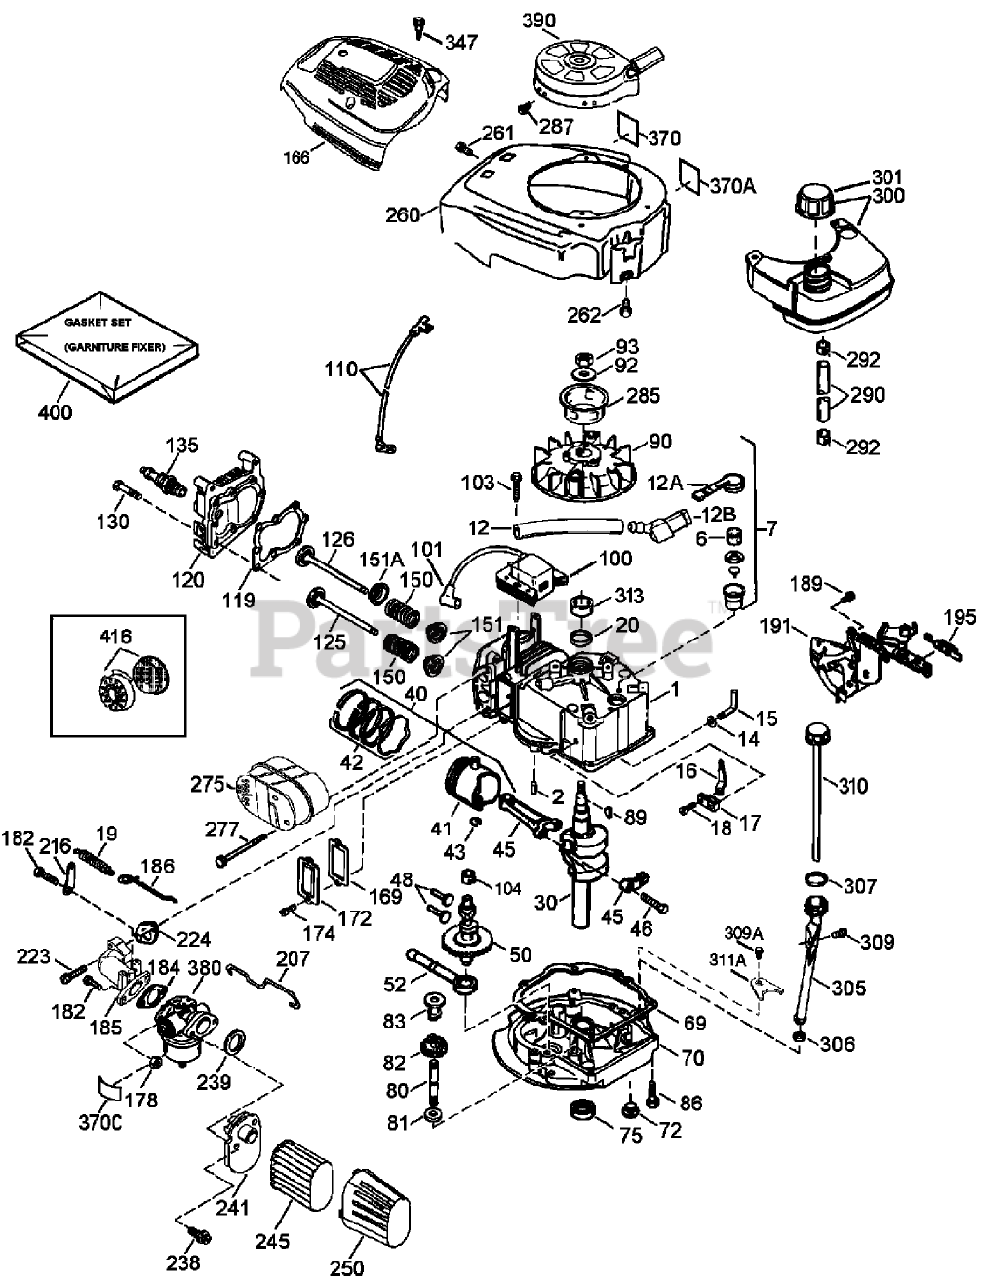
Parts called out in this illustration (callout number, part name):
313	Spacer
347	Screw (10-32 x 27/32)
370	Decal-Warning
370A	Decal-Lubrication
370C	Decal-Primer
380	Carburetor (Incl. Ref. #184 of Engine Parts List)
390	Rewind Starter ASM
400	Gasket Set
416	Spark Arrestor Kit
